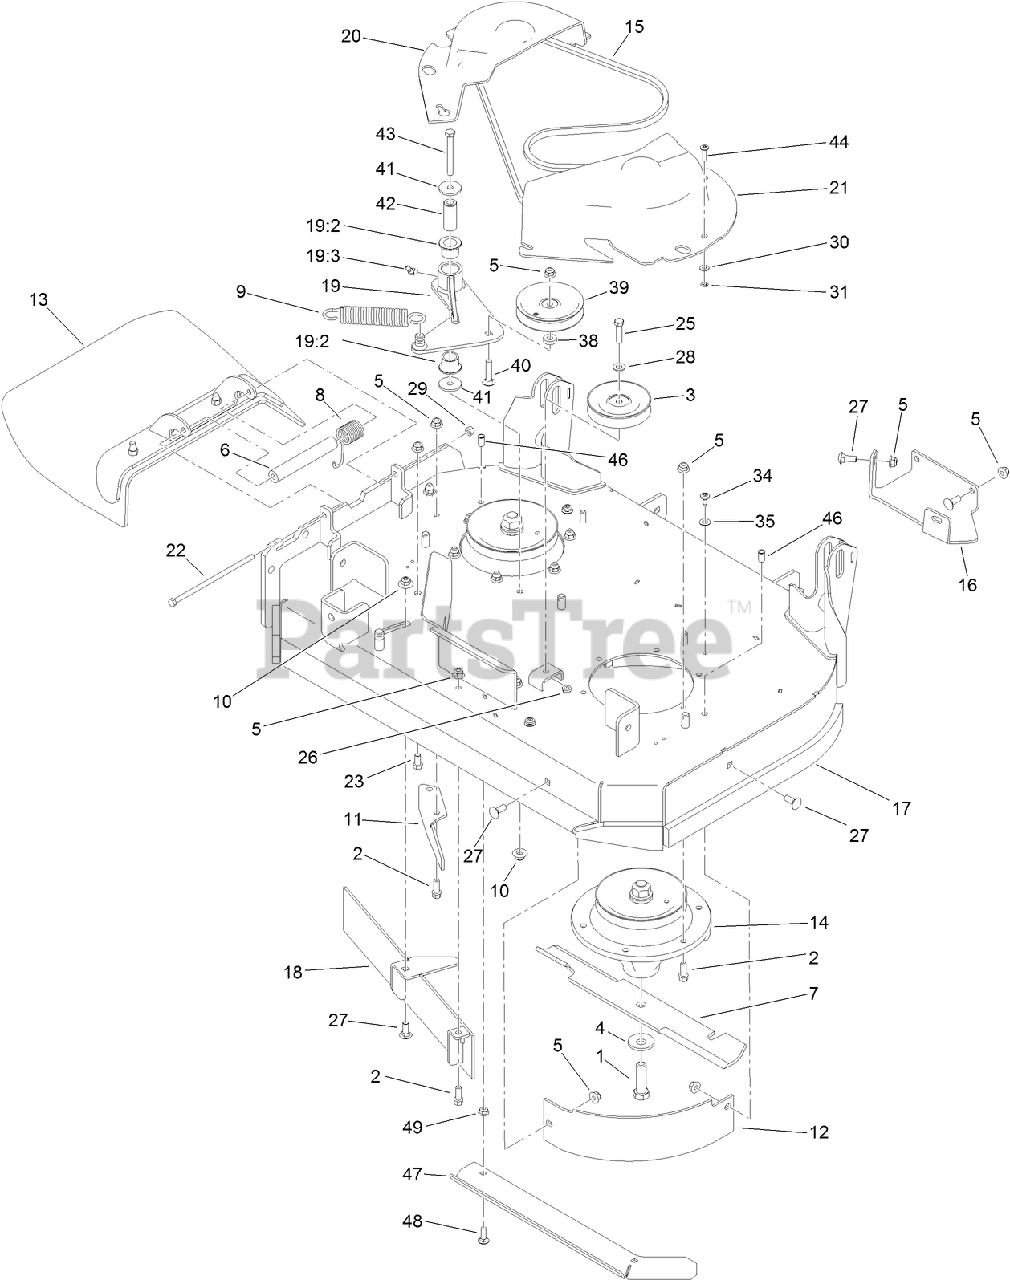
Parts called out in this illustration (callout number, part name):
1	SCREW-BLADE
2	SCREW-HWH
3	PULLEY-IDLER
4	Washer-Blade Bolt, Heavy
5	NUT-HF, NI
6	SPACER
7	BLADE-18IN, HI FLOW
8	SPRING-TORSION
9	SPRING-EXTENSION
10	NUT-FLANGE, NI
11	BAFFLE-DISCHARGE
12	BAFFLE-FRONT, LH
13	DEFLECTOR ASM
14	SPINDLE ASM
15	BELT-V
16	PLATE-SKID
17	DECK AND DECAL ASM
18	FRONT BAFFLE ASM
19	IDLER ARM ASM
19:2	BUSHING
19:3	FITTING-LUBE, 45 DEG
20	COVER-BELT, RH
21	COVER-BELT, LH
22	SCREW-HH
23	SCREW-HH
25	SCREW-HH
26	NUT-LOCK, NI
27	BOLT-CARR
28	WASHER-FLAT
29	NUT-LOCK, NI
30	WASHER-FLAT
31	NUT-RETAINER
34	SCREW-SHOULDER
35	WASHER-THRUST
38	SPACER
39	PULLEY-IDLER
40	SCREW-CARR
41	WASHER
42	SPACER-PLAIN
43	SCREW-HH
44	SCREW-TTH
46	INSERT-NUT
47	EXTENDER-DECK
48	BOLT-CARR
49	NUT-HF, NI
